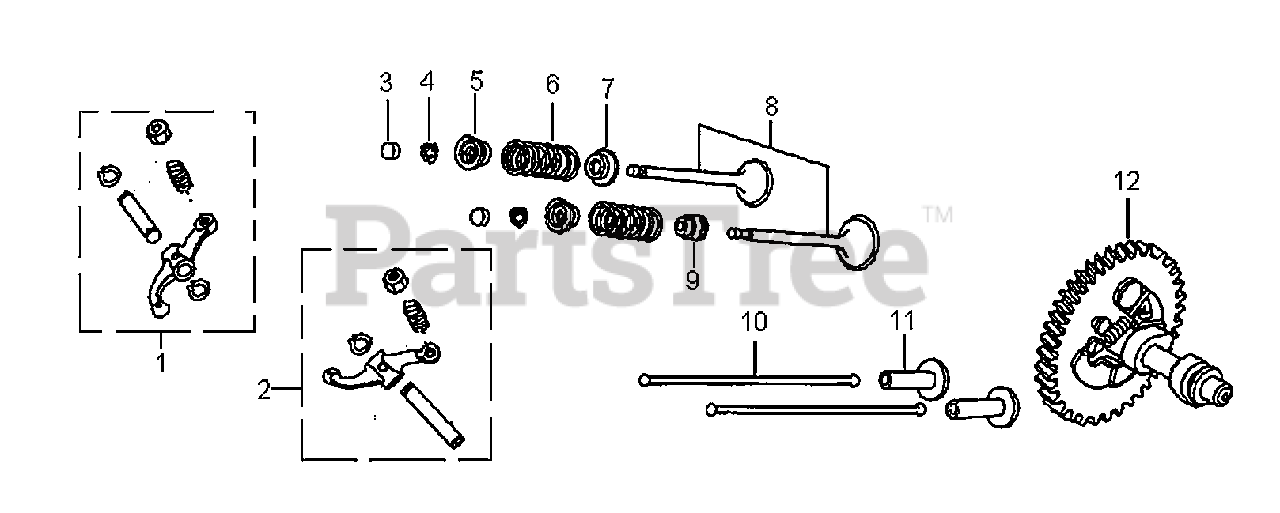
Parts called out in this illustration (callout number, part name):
1	ROCKER ARM ASSY.
2	ROCKER ARM ASSY.
3	ROTATOR'VALVE
4	VALVE LOCKER
5	RETAINER'VALVE SPRING
6	SPRING'VALVE
7	SEAT'VALVE SPRING
8	VALVE ASSY.
9	SEAL'VALVE STEM
11	LIFTER ' VALVE
12	CAMSHAFT ASSY
